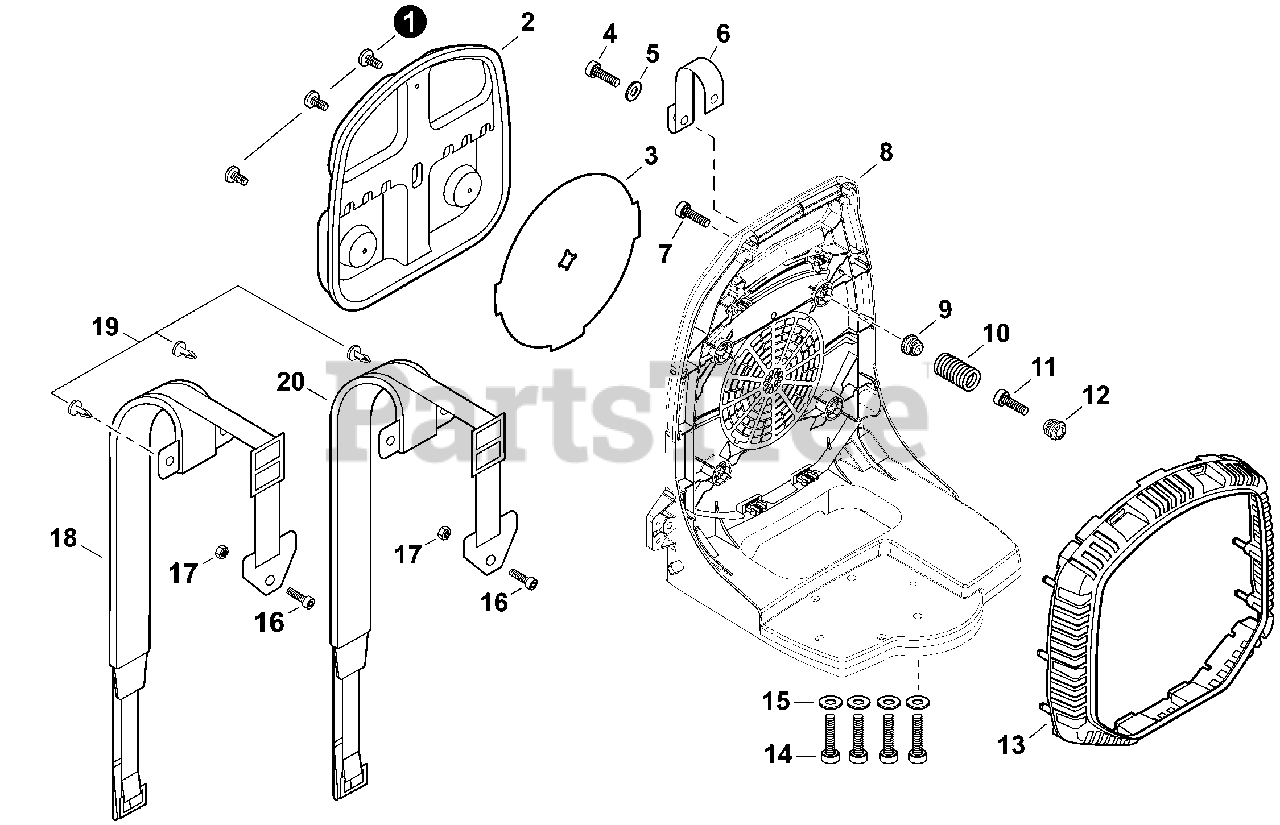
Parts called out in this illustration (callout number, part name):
2	CUSHION, BACKPACK
3	INSERT, COLD WEATHER
4	BOLT, TORX 5×20
5	WASHER 5.5×16×2T
6	STRAP, SAFETY 1.2×100
7	BOLT, TORX 5×20
8	FRAME, BACKPACK
9	HOLDER, SPRING
10	SPRING, COMPRESSION
11	BOLT, TORX 5×16
12	HOLDER, SPRING
13	GUARD, LEAF
14	SCREW 5×25
15	WASHER 5.5×16×2T
16	BOLT, TORX 5×30
17	NUT, LOCK M5
18	HARNESS ASSY, LEFT
19	CLIP 7/16"
20	HARNESS ASSY, RIGHT
